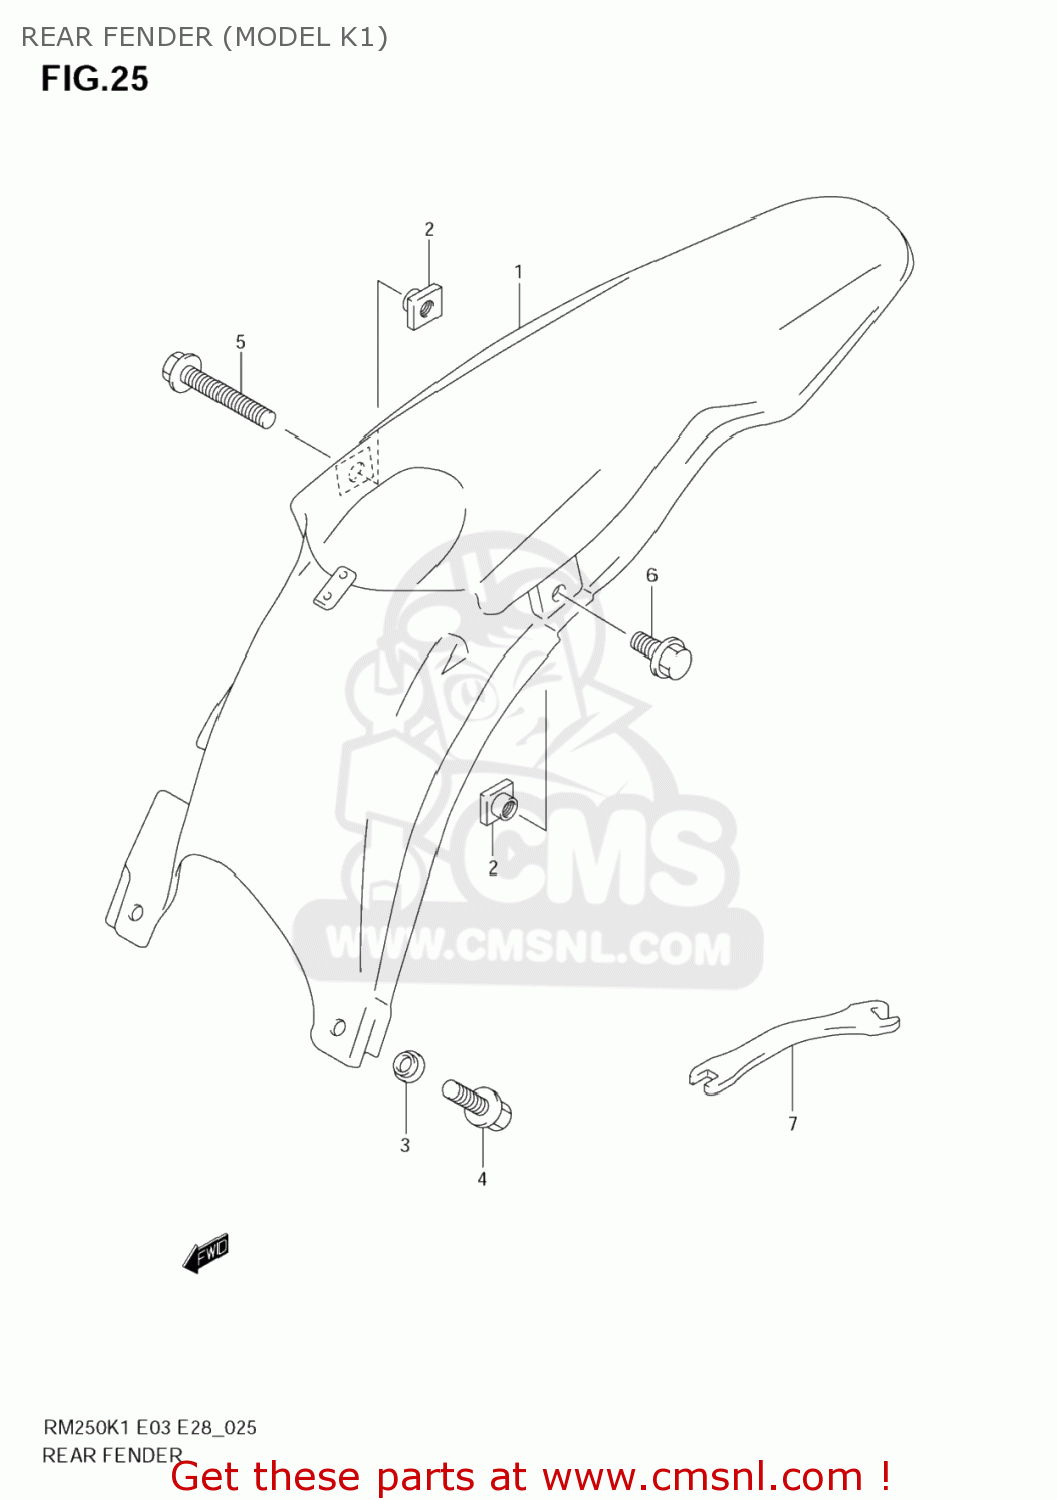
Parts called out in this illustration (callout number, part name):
1	FENDER,REAR
2	NUT
3	WASHER
4	SCREW
5	BOLT
6	BOLT
7	SPANNER,OPEN
